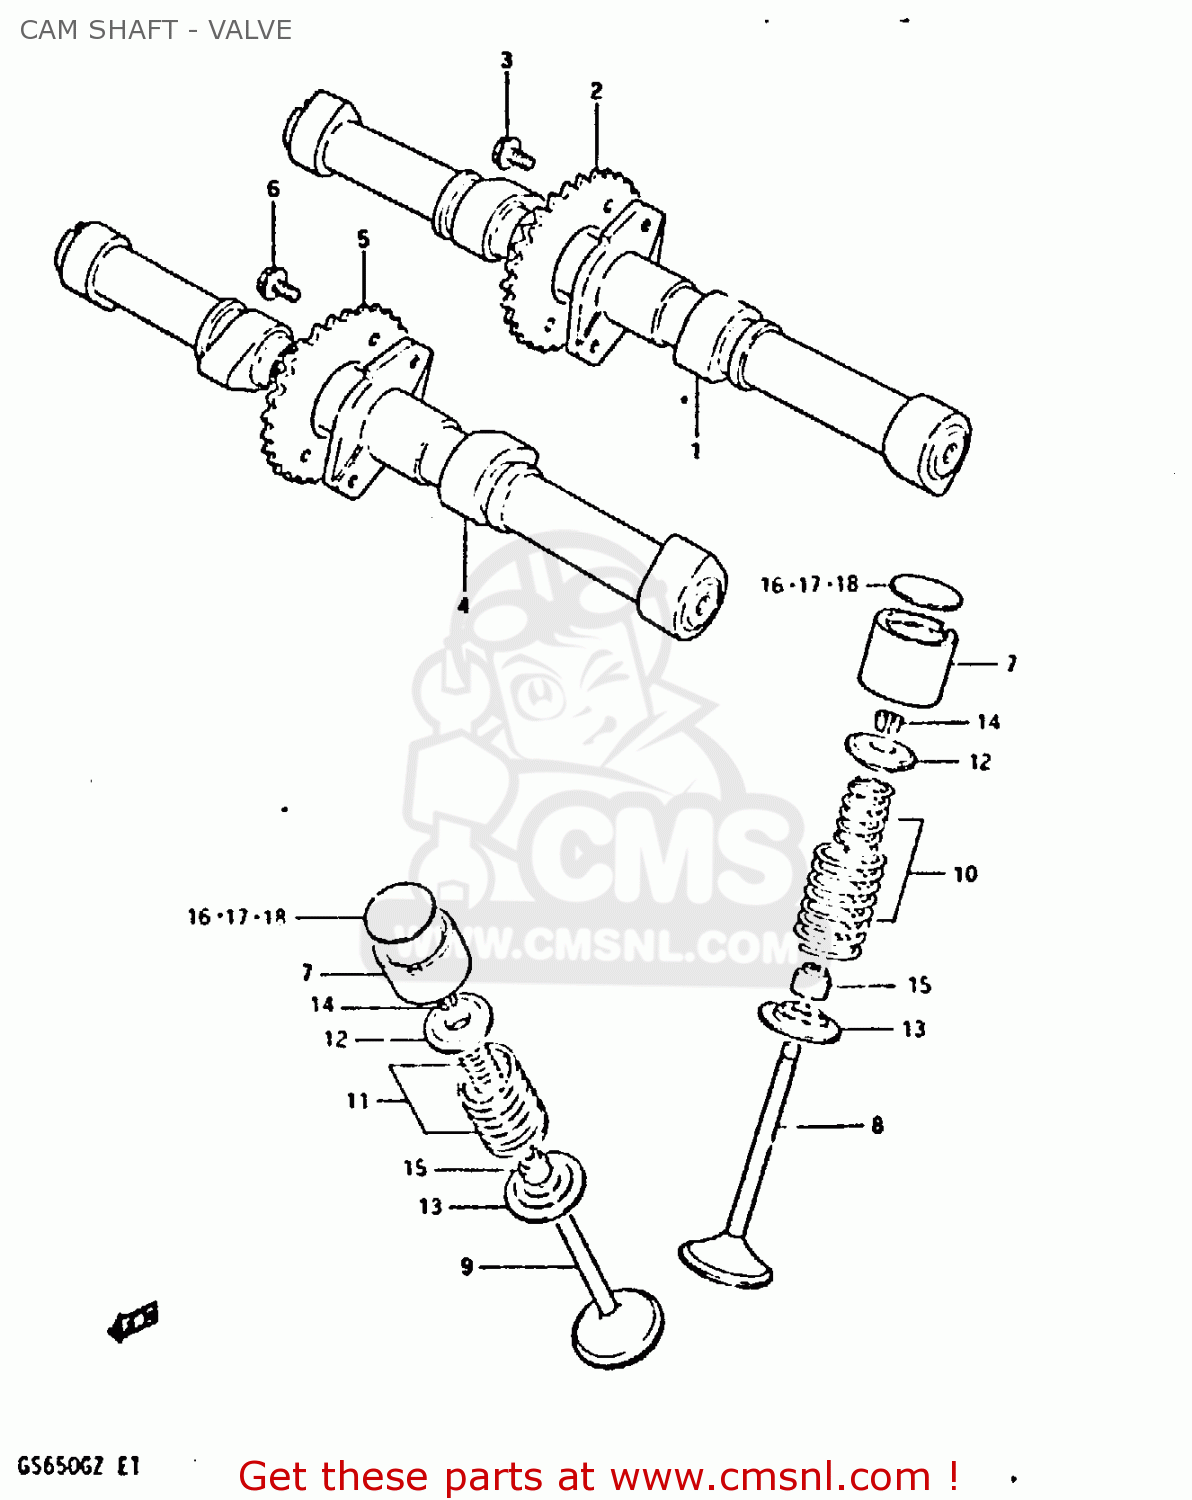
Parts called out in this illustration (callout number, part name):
1	CAMSHAFT,INTAKE
2	SPROCKET,INTAKE CAMSHAFT
3	BOLT(7X11)
4	CAMSHAFT,EXHAUST
5	SPROCKET,EXHAUST CAMSHAFT
6	BOLT(7X11)
7	TAPPET
8	VALVE,INTAKE
9	VALVE,EXHAUST
10	SHIM,TAPPET
11	SHIM,TAPPET
12	RETAINER,VALVE SPRING
13	SEAT,VALVE SPRING
14	COTTER VALVE
15	SEAL,OIL(7X14.4X9)
16	SHIM,TAPPET
17	SHIM,TAPPET
18	SHIM,TAPPET
